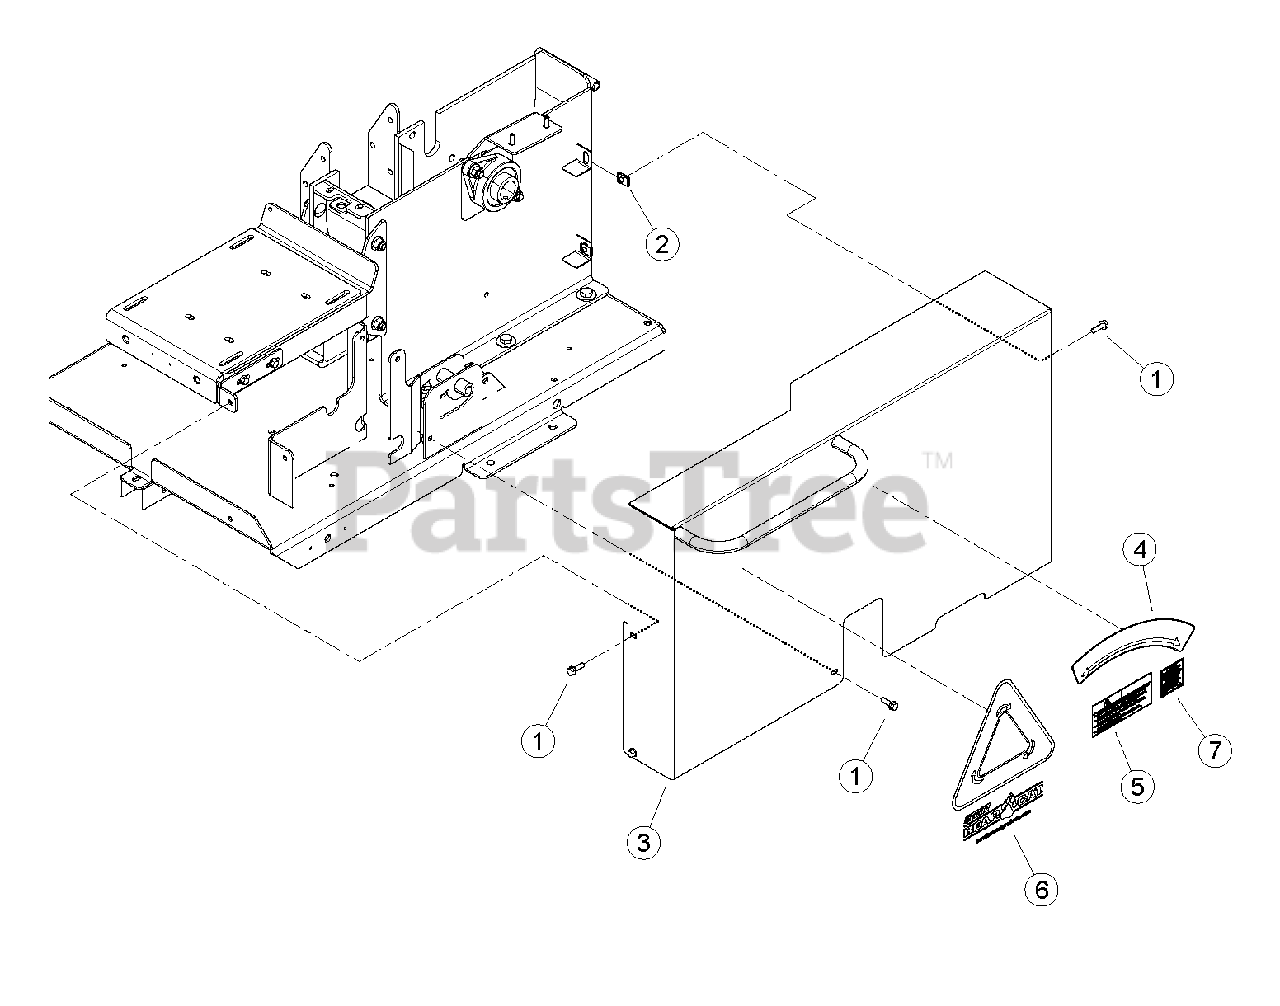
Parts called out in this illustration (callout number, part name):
1	BOLT, 5/16 X 1 FLANGE NC
2	NUT, 5/16"-18 TINNERMAN U-TYPE
3	ASSEMBLY, SHIELD WITH DECALS
4	DECAL, START/ENGAGE
5	DECAL, MUTILINGUAL MANUAL
6	DECAL, CHIP IT LARGE
7	DECAL, SPARK ARRESTOR
